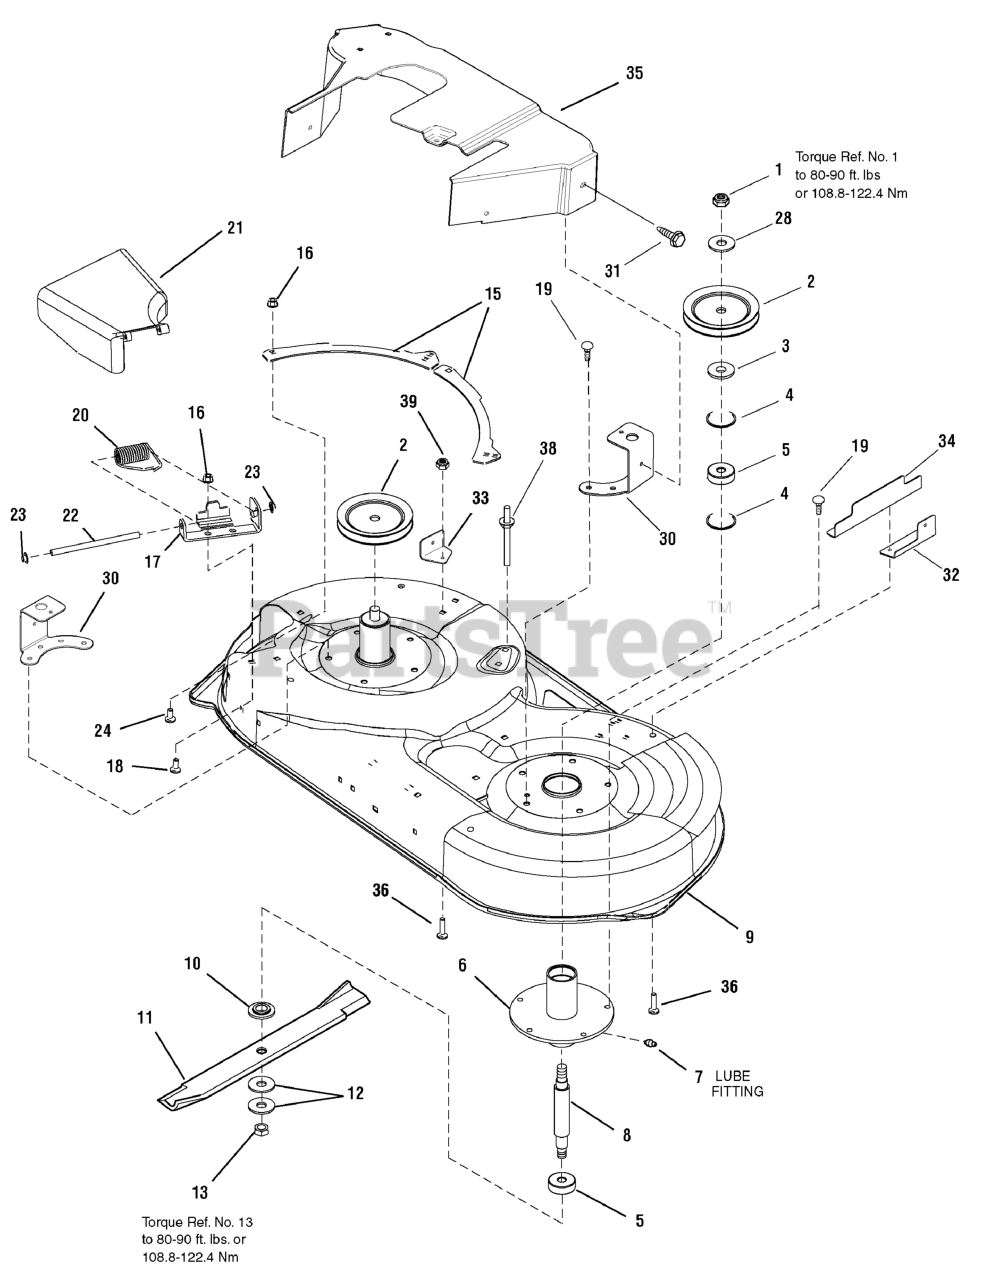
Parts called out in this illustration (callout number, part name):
1	NUT, Hex Nylock, 5/8
2	PULLEY, Drive
3	SPACER, Pulley
4	RING, Retaining
5	BEARING, Spindle
6	TUBE & PLATE ASSEMBLY, Spindle
7	LUBE, Fitting
8	SHAFT, Spindle
9	HOUSING, 42"
10	WASHER, Spidle Blade
11	BLADE
12	WASHER, Belleville
13	NUT, Hex, 9/16
15	PLATE, Rear
16	NUT, ESNA, 5/16
17	BRACKET, Hinge
18	BOLT, Carriage, 5/16 - 18 x 3/4
19	SCREW, Taptite, 3/8 - 16 x 3/4
20	SPRING, Torsion
21	DEFLECTOR
22	ROD, Deflector
23	PUSHNUT
24	CAPSCREW, Hex Head, 5/16-18 x 1
28	LOCKWASHER, Internal Tooth, 5/8
30	SUPPORT, Pulley Cover
31	SCREW, Taptite, 5/16 - 18 x 1/2
32	BRACKET, Cover, Mounting, Left
33	BRACKET, Cover, Mounting, Right
34	BRACKET, Guard, Left
35	COVER, 42in Deck
36	BOLT, Shoulder, 5/16-18 x 5/8
38	STANDOFF
39	NUT, Hex Flange, Two Way Lock, 3/8-16
